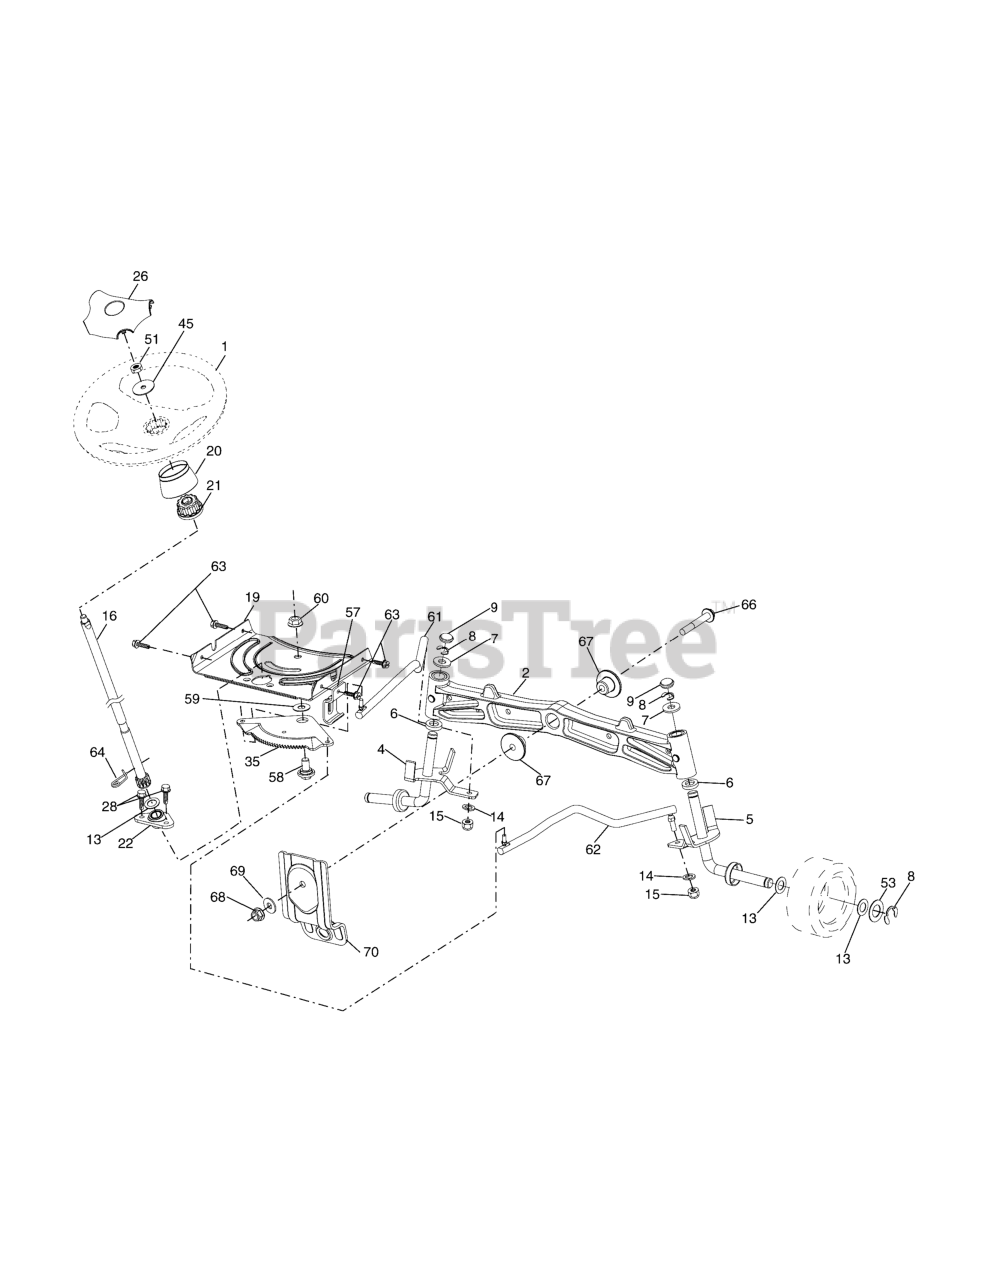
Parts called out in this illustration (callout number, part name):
1	Wheel, Steering
2	Axle Asm., Front
4	Spindle Asm., LH
5	Spindle Asm., RH
6	Bearing, Race Thrust Harden
7	Washer 25/32 x 1-5/8 x 16 Ga.
8	Ring, Clip #T5304-75
9	Cap, Spindle
13	Washer 25/32 x 1-1/4 x 16 Ga.
14	Washer, Lock Hvy Hlcl Spr 3/8
15	Nut, Crown Lock 3/8-24 unf
16	Shaft Steering
19	Plate Steering
20	Boot, Steering
21	Adapter, Wheel Steering
22	Bushing, Strg. Blk
26	Insert, Wheel Steering
28	Screw 3/8-16 x 3/4
35	Gear, Sector Plate
45	Washer 9/16 x 2-3/8 x 12 Ga.
51	Nut Hex Jam Toplock 1/2-20 unf
53	Washer Hardened .793 x 1.637 x .060
57	Bracket Upstop
58	Bolt Shoulder Sector Pivot CFM
59	Washer Thrust Sector Steering
60	Nut Flange Lock 5/8-11
61	Draglink, LH
62	Draglink, RH
63	Screw 5/16-18 x 3/4
64	Retainer Clip Spring Steering
66	Bolt Hex Fghd 7/16-14 x 3 Serr
67	Bushing PM Front Axle
68	Nut Lock Flange 7/16-14 Gr. 5
69	Washer 1.5 x .505 x .118
70	Bracket Deck Susp. Front
